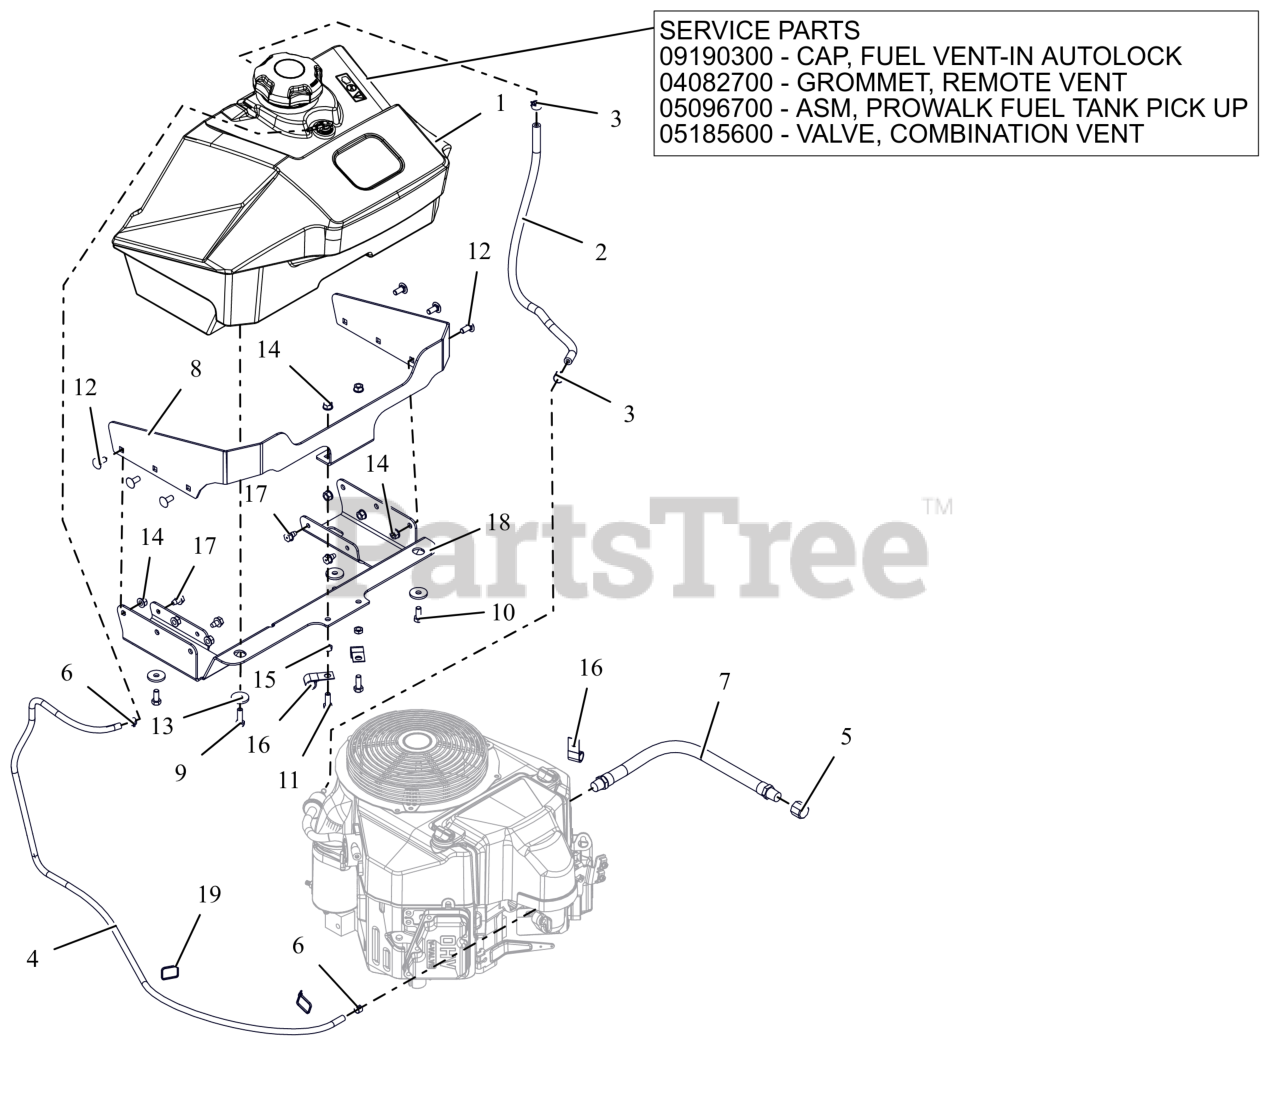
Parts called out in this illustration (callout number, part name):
1	TANK, PRO-WALK
1	CAP, FUEL - 3.50 RATCHET INLET VENT
1	GROMMET, REMOTE VENT NITRILE
1	ASM, PROWALK FUEL TANK PICK UP
1	VALVE, COMBINATION VENT 3/16
2	HOSE, .25 LOW-PERM BULK GAS
3	CLAMP, FUEL LINE
4	HOSE, .188 LOW-PERM BULK GAS
5	PIPE CAP 3/8 NPT FEMALE
6	CLAMP-HOSE, SPRING .188
7	DRAIN, M20 OIL
8	BRKT, FUEL TANK MTG (RED)
9	BLT,HEX .31-18X1.00 G5 ZCC
10	BLT,HEX .31-18X.75 G5 ZCC
11	BLT, HEX .31-18X.875 G5 ZCC
12	BLT, RHSSN.31-18X.750 G5 ZCC
13	WSHR, FLT .340X1.125X.135 ZCC
14	NUT,LK-CTR-FLG .31-18 GF ZCC
15	NUT-JAM .312-18 G2 ZCC
17	SCR,TAP .312-18X.50 HWH TR ZCC
18	BRKT, FUEL TANK MTG (BLACK)
19	CABLE TIE LG 5-1/2
